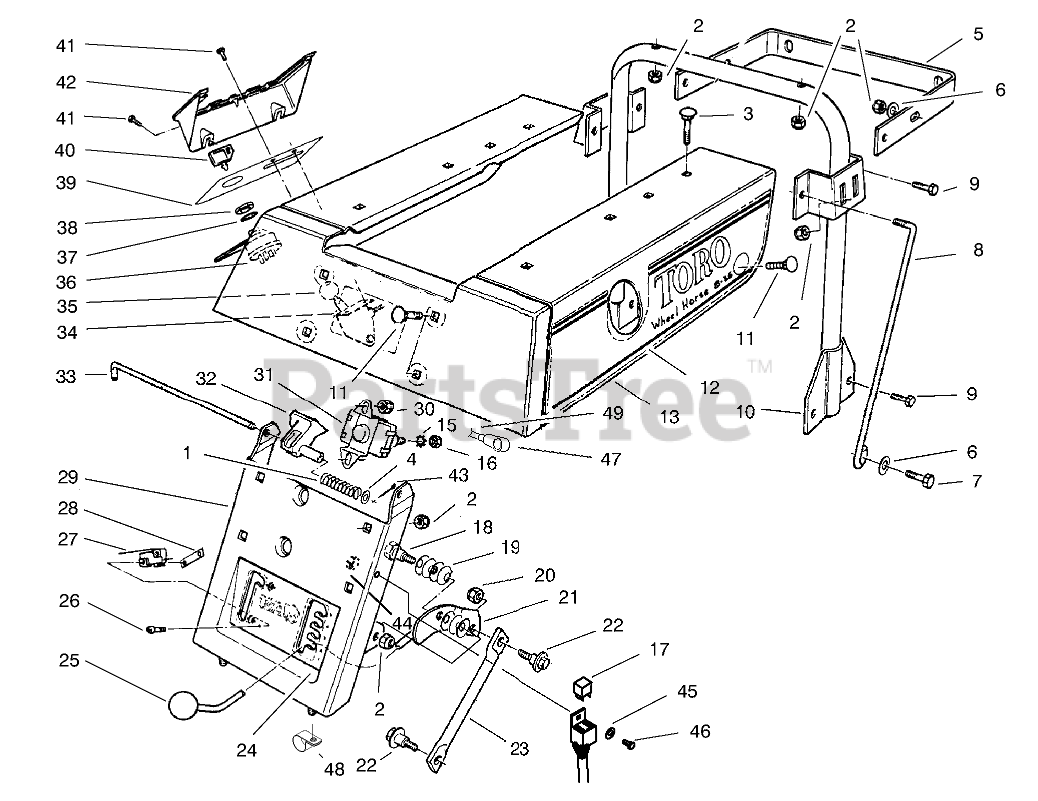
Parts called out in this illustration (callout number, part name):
1	SPRING-COMPRESSION
2	NUT-LOCK, NI
3	SCREW-CARR
4	WASHER-FLAT
5	STANDBAR
6	WASHER-PLAIN
7	SCREW-HH
8	BRACE-SEAT SUPPORT
9	SCREW-HH
10	SEAT SUPT WA (BLACK)
11	BOLT-CARR
12	DECAL - RH SIDE PANEL
13	SEAT BODY WA (RED)
15	WASHER-LOCK
16	NUT-JAM
17	RELAY
18	BOLT-SHOULDER
19	WASHER-BELLEVILLE
20	NUT-LOCK, NI
21	HOC HDLE WA
22	BOLT-SHOULDER
23	LINK-HOC
24	DECAL - HOC
25	KNOB-CONTROL
26	Screw
27	SWITCH-MICRO
28	NUT-SPEED
29	FRT SEAT SUP WA RED
30	NUT-LOCK, NI
31	Solenoid
32	PROP-SEAT
33	ROD-SEAT BASE
34	CONTROL-THROTTLE
35	KNOB-CONTROL
36	Switch-Ignition (Incl. Ref. #37 & 38)
37	WASHER-TOOTH, INTERNAL
38	NUT-HH
39	DECAL - CONTROL PANEL
40	KEY-IGNITION
41	SCREW-THD FORM, HWH
42	COVER-CONTROL PLATE
43	PIN-COTTER
44	NUT-LOCK, NI
45	WASHER-FLAT
47	BOOT-INSULATOR, TERMINAL
48	CLIP-FUEL LINE
49	ASM - CABLE
